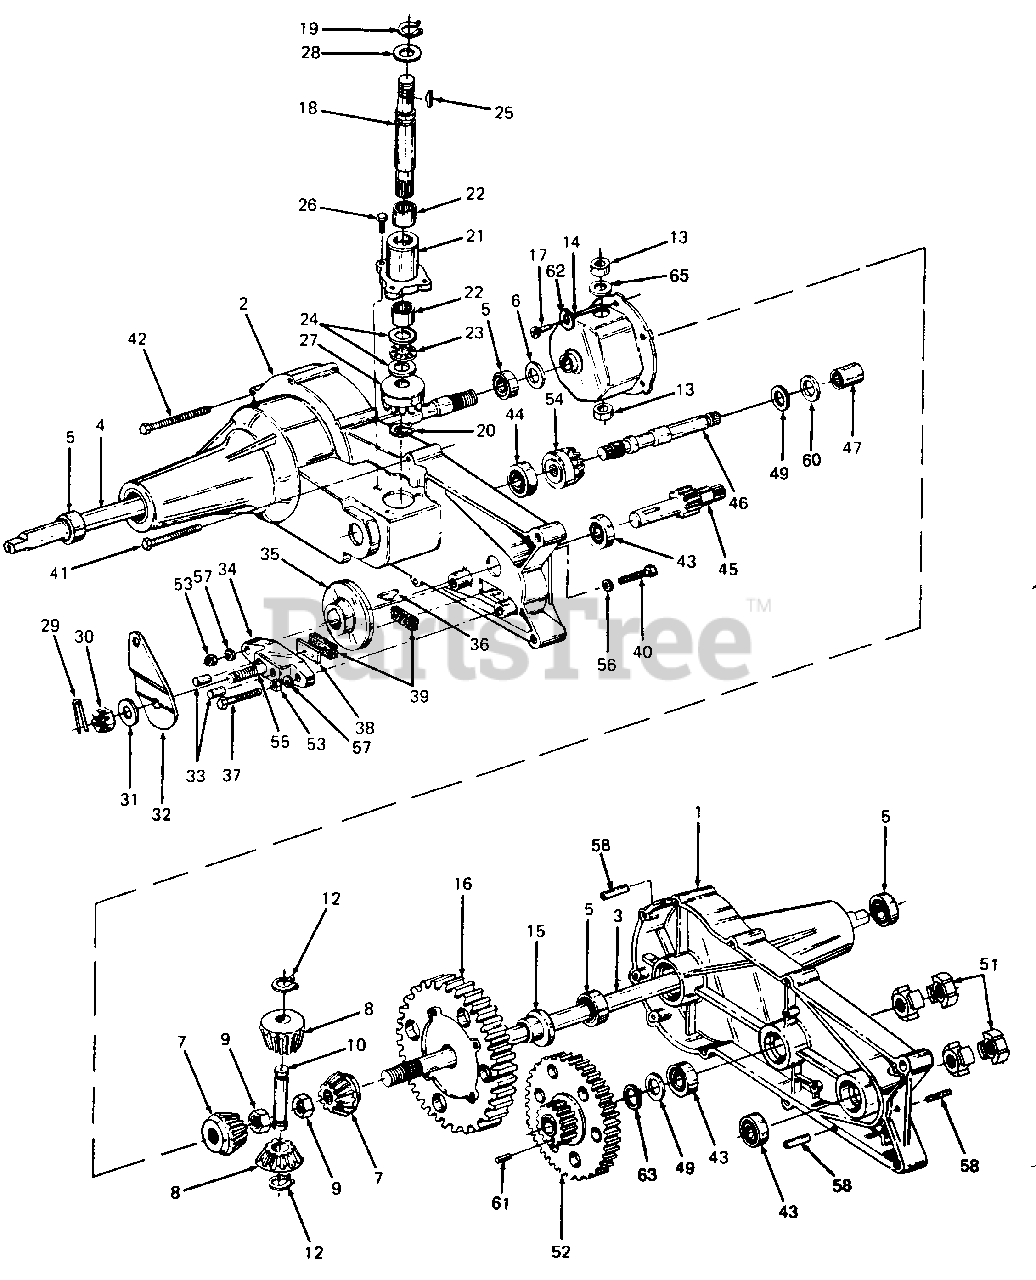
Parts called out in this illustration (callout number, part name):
1	Housing Half, L.H.
2	Housing Half, R.H.
3	Axle, L.H.
4	Axle, R.H.
5	Bearing, Ball
6	Washer, Flat, .76" x 1-1/8" x 306 Thk Hdn.
7	Gear Miter
8	Gear Miter
9	Nut, Hex Jam Patch Lock, 1/2-20
10	Shaft, Cross
12	Ring, Snap
13	Bearing, Thrust
14	Housing Ass'y. Differential
15	Bearing, Flange, 75" I.D. x .587"
16	Gear, Differential, 72 Tooth
17	Torx Hd. AB-Tap Scr. 1/4 X .62" Lg.
18	Shaft, Input
19	Ring, Snap
20	Ring, Retaining, Ext. 7/16" Dia.
21	Bearing, Input Housing
22	Bearing, Needle, 518" I.D. x .50" Lg.
23	Bearing, Thrust
24	Washer, Flat, 518" I.D. x 1.12" O.D. x .030" Thk.
25	Key #4 Hi-Pro, 3/32" x 5/8" Dia. (Hdn.)
26	Screw, Hex Patch Lock, 1/4-20 X 3/41' Lg.
27	Gear, Input Pinion, 17 Tooth
28	Washer, Flat, .62" I.D. x 1.0" O.D. x 030" Thk.
29	Pin, Cotter
30	Nut, Castle, 5/16-24 Thd.
31	Washer, Flat, .343" x .88" x .062" Thk.
32	Arm, Brake Actuator
33	Pin, Actuating, 5/16 Dia.
34	Yoke, Brake
35	Disc, Brake
36	Key, Hi-Pro, 3/16" x 518" Dia.
37	Screw, Hex Patch Lock, 1/4-20 x 1.5 Lg.
38	Plate, Puck
39	Puck, Brake
40	Screw, Hex Cap, 1/4-20 x 1.5" Lg.
41	Screw, Hex Self-Tap, 1/4-20 x 2.0" Lg.
42	Screw, Hex Self-Tap, 1/4-20 x 2.75" Lg.
43	Bearing, Ball
44	Bearing, Ball
45	Shaft, Pinion w/11 Tooth Gear
46	Shaft, Drive
47	Bearing, Needle
49	Washer, Flat, 5/8" x 1.12" x 060" Thk.
51	Coupling
52	Gear, Tooth 60 & 17
53	Nut, Hex Jam, 1/4-20 Thd.
54	Gear, Drive Pinion, 17 Tooth
55	Bolt, Square Hd. 5/16-24 Thd.
56	Washer, Flat, .265" x 938" x 12" Thk.
57	Washer Lock, 1/4" I.D.
58	Pin, Roil, 3/16 Dia. x 50" Lg.
60	Bronze Thrust Brg. 5/8" I.D.
61	Dowel Pin 3/32" x 1/4"
62	Washer, Spring Lock 1/4" I.D.
63	Seal, Grease
65	Washer, Flat, .62" I.D. x 1 on O.D. x 020" Thk.
